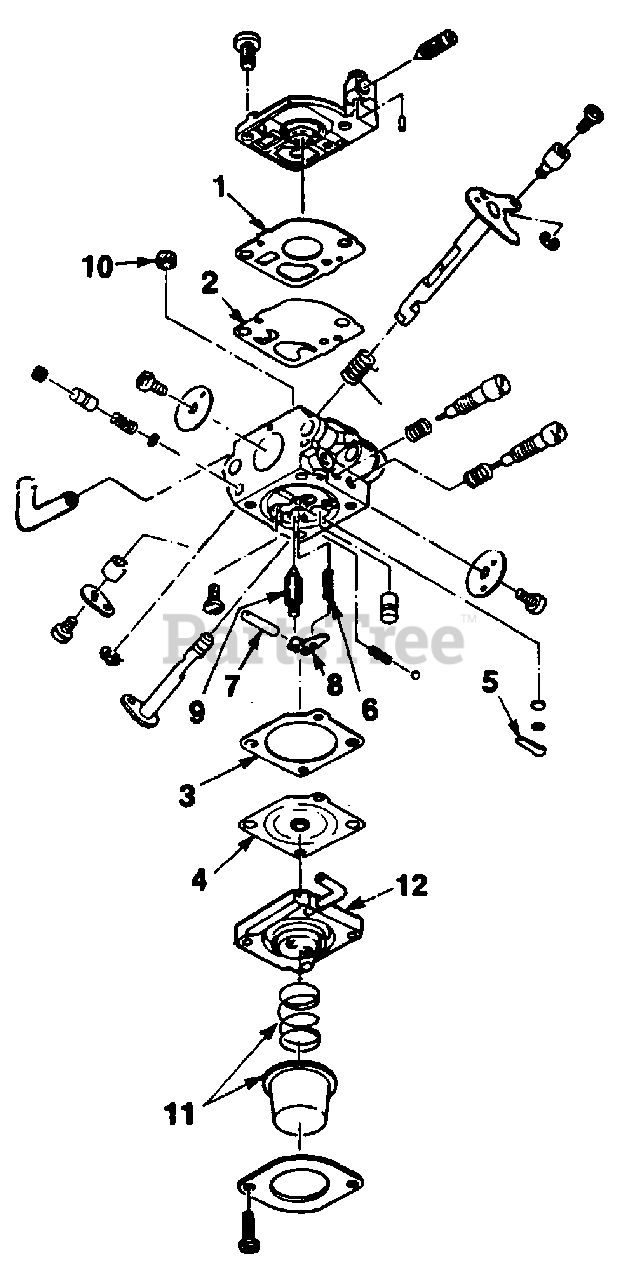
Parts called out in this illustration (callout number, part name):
1	GASKET/Diaphragm Kit
2	GASKET/Diaphragm Kit
3	GASKET/Diaphragm Kit
4	GASKET/Diaphragm Kit
5	Repair Kit
6	Repair Kit
7	Repair Kit
8	Repair Kit
9	Repair Kit
10	Repair Kit
11	Primer Bulb
12	Primer Base
